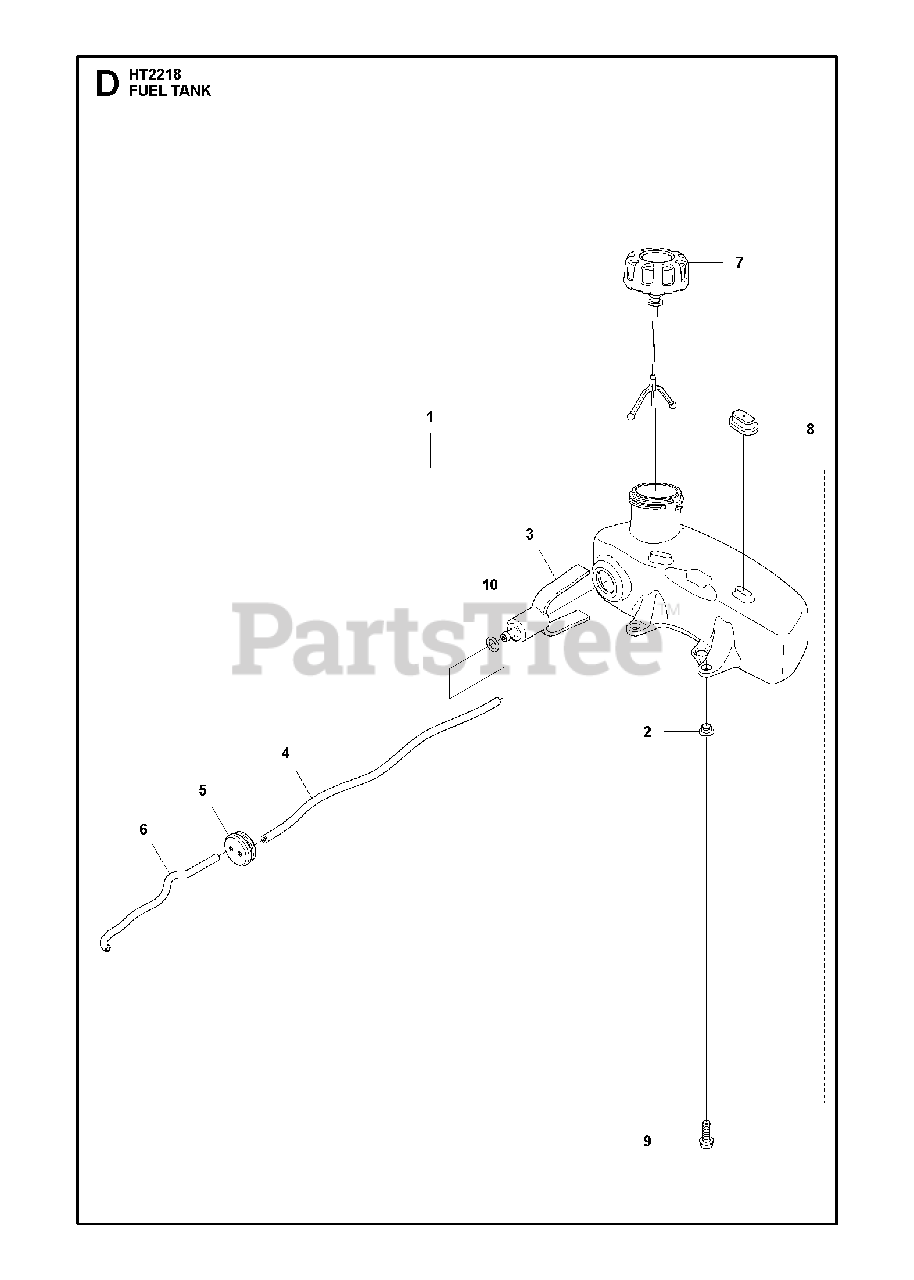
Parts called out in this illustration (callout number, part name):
1	TANK ASSY.
2	RIVET TUBULAR
3	FUEL FILTER
4	FUEL HOSE
5	GROMMET
6	HOSE
8	FUEL TANK ISOLATOR
10	THROTTLE LOCK
